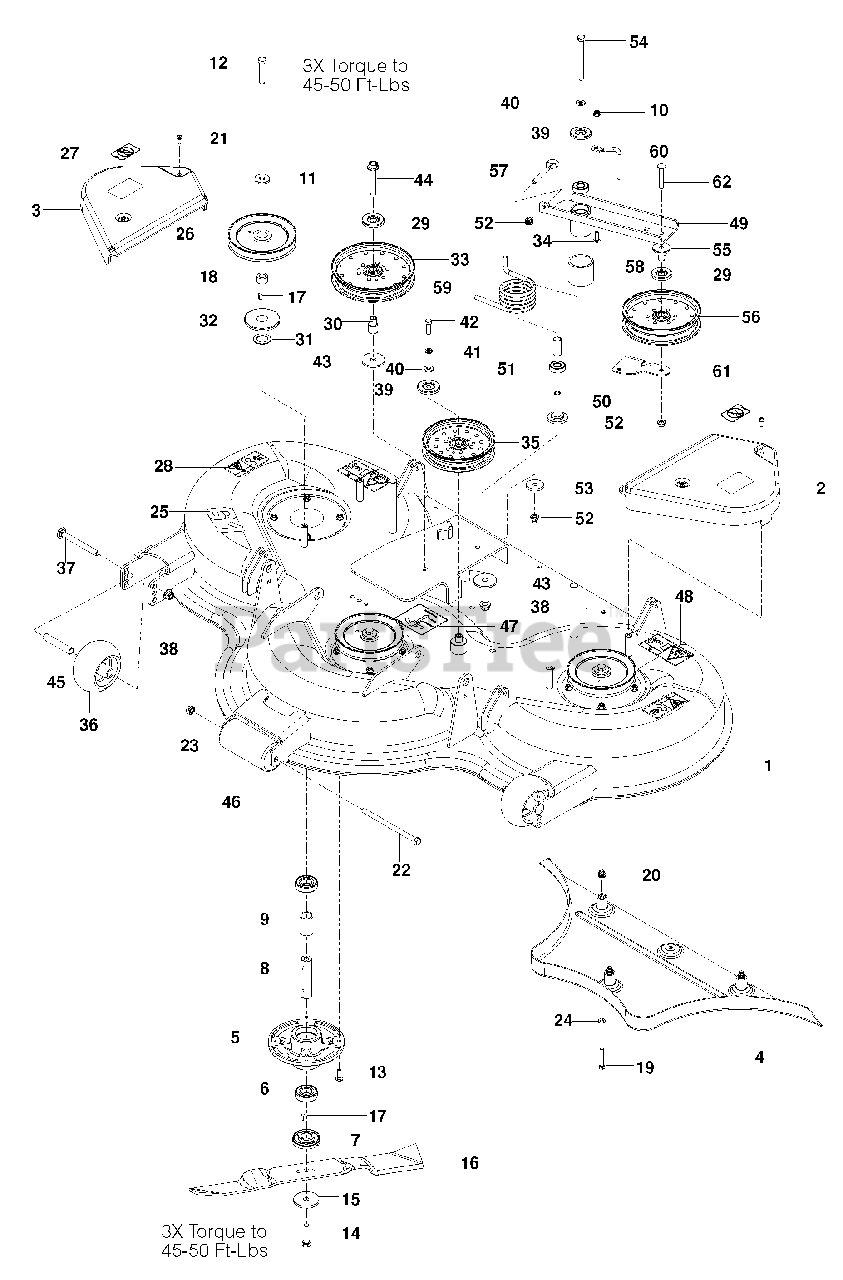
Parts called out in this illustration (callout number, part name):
1	DECK w/ SAFETY DECALS
2	BELT SHIELD, LT
3	BELT SHIELD, RT
4	MULCH PLUG, 155
5	BEARING HOUSING
7	BUSHING, BLADE
10	NUT 5/16-18 FLANGE NYLOC
11	WASHER 1/2
12	HCS M12 x1.75 x 60, GR8.8
13	RHSNB 5/16-18 x 1
14	HCS M12 x 1.75 x 50, GR8.8
16	BLADE, C155
18	KEY RETAINER
19	HCS M8 x 1.25 x 50, GR8.8
20	BLIND RIVET NUT
21	SCREW 1/4-20 x 5/8 THD FRM
22	HCS 7/16-14 x 7
23	NUT 7/16-14 CTRLK GR A
24	WASHER 5/16 SAE
25	LABEL
26	PULLEY, 61
27	DECAL, NO STEP
28	DECAL, DNGR BELT DRIVE
29	SHIELD, DUST
30	SPACER, IDLER
31	WASHER 1.06
32	TOP DUST CAP
33	PULLEY, IDLER, 7" NARROW
34	RHSSNB 5/16-18 x 1
35	PULLEY, IDLER, 6" NARROW
36	ROLLER, GAUGE
37	RHSNB 1/2-13 x 4 3/4
38	NUT 1/2-13 FLG NYLOC
39	SHIELD, DUST
40	WASHER 3/8, THICK
41	WASHER 3/8 SPLT LOCK
42	HCS 3/8-16 x 11/4
43	WASHER, HEAVY
44	HFFS 1/2-13 x 3
45	TUBE, ROLLER AXLE
46	ROLLER
47	DECAL, BELT ROUTING
48	DECAL, SEVERING
49	ARM, IDLER
50	BEARING, IDLER PIVOT
51	BEARING, BALL
52	NUT 3/8-16 FLG NYLOC
53	WASHER, HEAVY
54	HCS 3/8-16 x 4 1/2 GR8
55	BEARING, IDLER ARM
56	PULLEY, IDLER 7"
58	SPACER, IDLER PIVOT
59	SPRING, TORSION
60	BELT KEEPER
61	BELT GUIDE
62	BOLT 3/8-16 x 2 1/2 CARRIAGE
